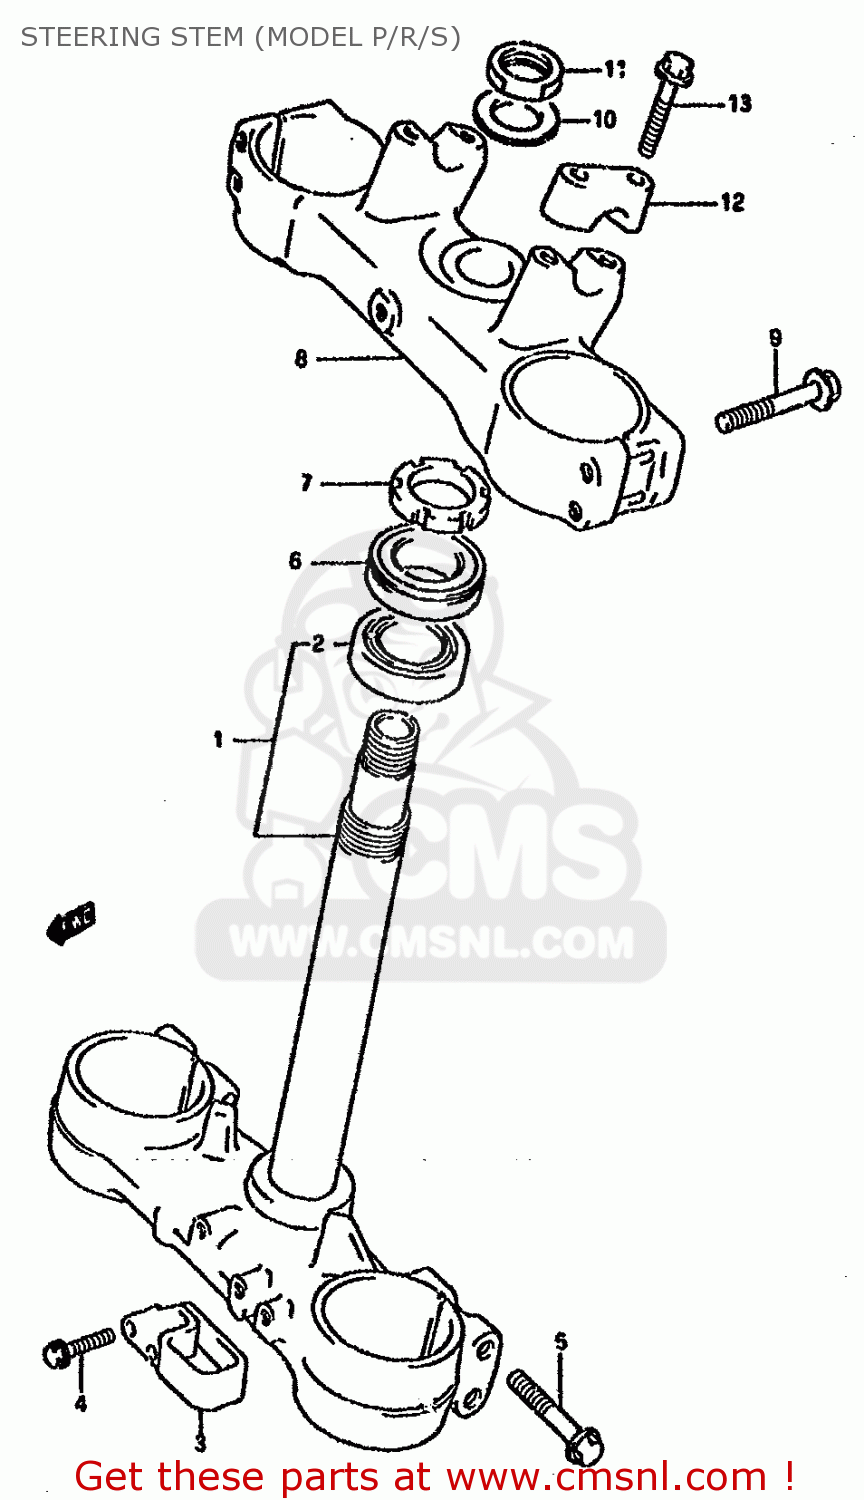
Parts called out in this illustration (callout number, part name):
1	STEM,STEERING
2	BEARING(30X52X16)
3	GUIDE,HOSE
4	BOLT,GUIDE
5	BOLT,STEM 8X45
6	BEARING(30X52X16)
7	NUT,STEERING
8	HEAD,STEERING STEM
9	BOLT,STEM 8X45
10	WASHER,STEM HEAD
11	NUT,STEM HEAD
12	HOLDER,HANDLEBAR
13	BOLT,HANDLE HOLDER(8X35)
